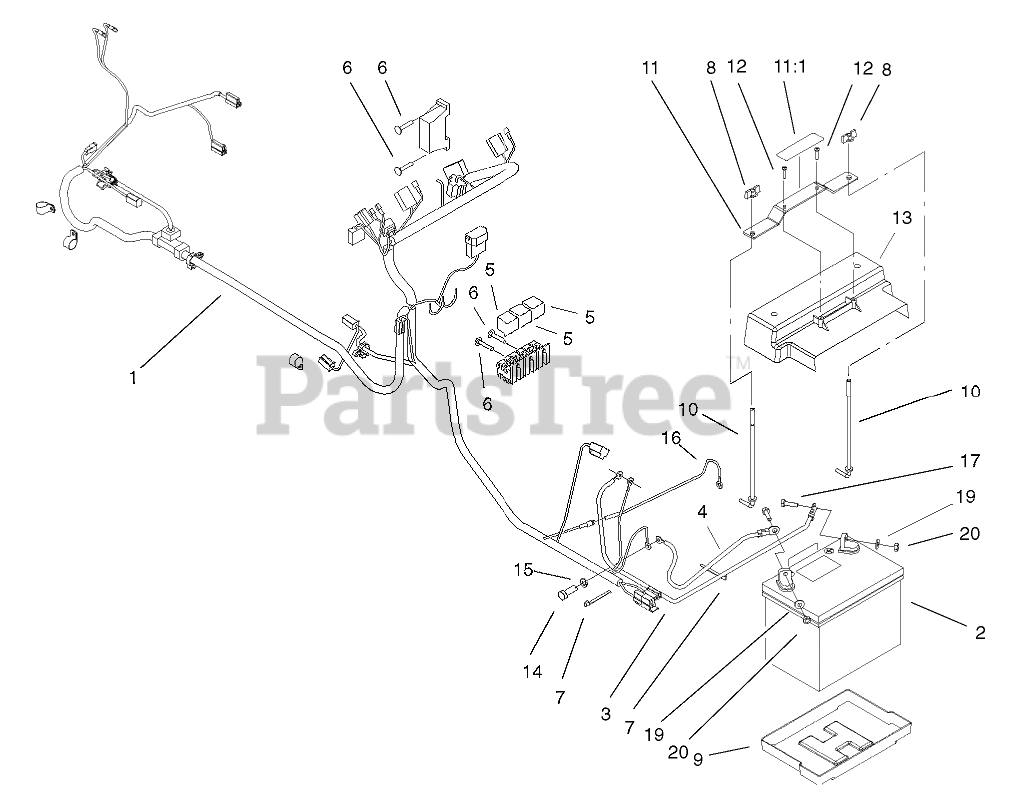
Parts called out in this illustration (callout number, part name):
1	HARNESS-WIRE
2	BATTERY-DRY
3	CABLE-BATTERY, RED 27IN
4	CABLE-BATTERY
5	RELAY
6	SCREW
7	TIE-CABLE
8	NUT-WING
9	TRAY-BATTERY
10	HOOK-RETAIN, BATTERY
11	STRAP ASM
11:1	DECAL-SURFACE, HOT
12	SCREW-PPH
13	SHIELD-BATTERY
14	SCREW-HHF
15	WASHER-LOCK
16	HARNESS-WIRE
17	SCREW-HH
19	WASHER-FLAT
20	NUT-LOCK, NI
